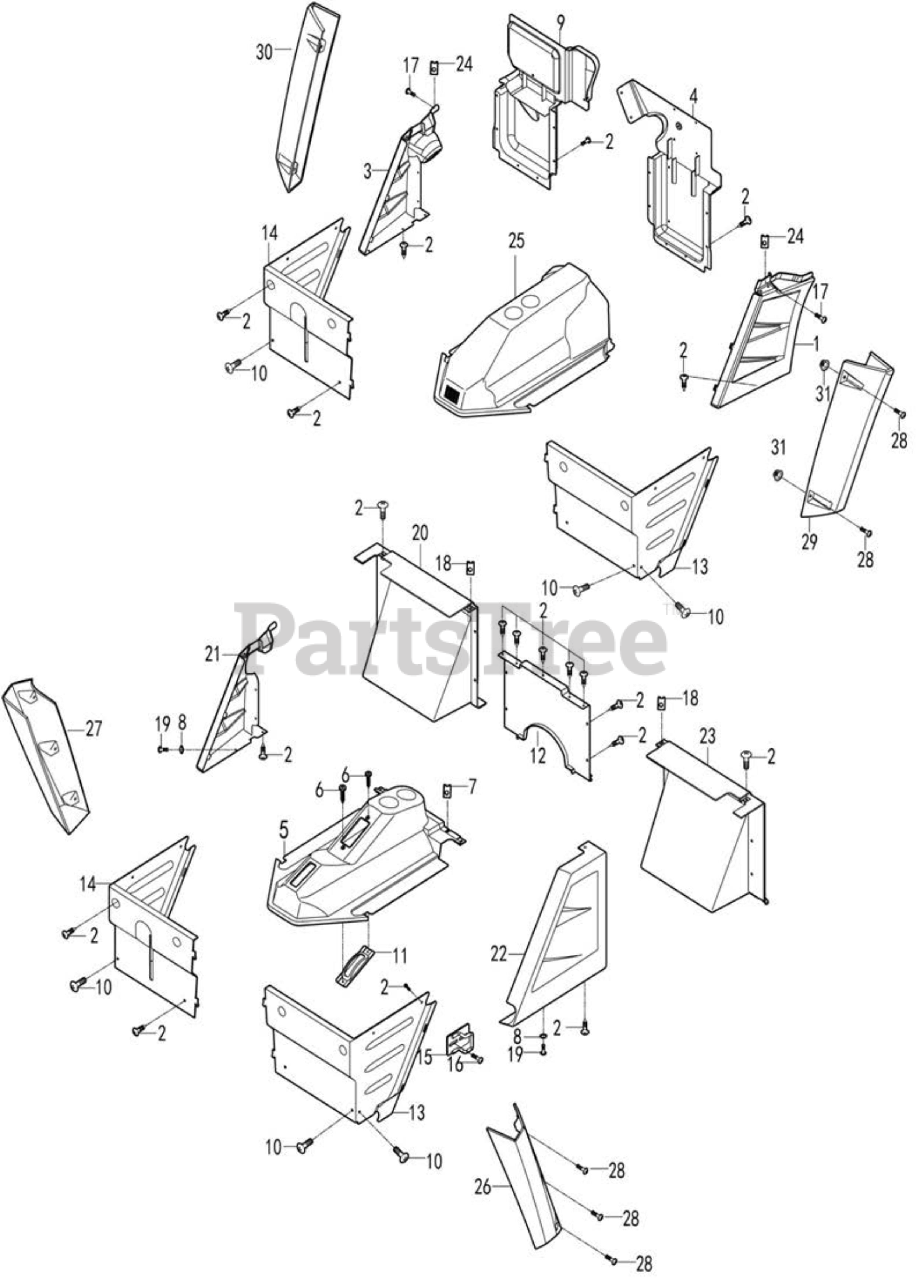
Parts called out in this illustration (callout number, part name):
1	Left Board I
2	Cross Large Plate Head Screw M6X16
3	Right Board I
4	Rear Fender I
5	Engine Cover Board
6	Socket Hexagon Flat Head Bolt M6X16
7	Nut clamp M6X2
8	Flat Washer 5
9	Rear Fender II
10	Expansion bolt(Plastic)
11	Parking Decorative Cover
12	Front Fender, Seat Cushion
13	Protective Plate under Seat
14	Lower Backplate, Seat Cushion
15	Door Locker Hook
16	Hexagon Flange Bolt M6X16
17	Cross Recessed Plate Head Screw M6X12
18	Nut clamp M6X2
19	Cross Large Plate Head Screw M5X16
20	Rear Right Backplate, Seat Cushion
21	Protective Plate(Left), Out of Cap
22	Protective Plate(Right), Out of Cap
23	Rear Left Backplate, Seat Cushion
24	Nut clamp M6
25	Middel Cover
26	Left fender, front cover
27	Right fender, front cover
28	Cross large plate head screw M6X20
29	Right fender, Rear body
30	Left fender, Rear body
31	Hexagon Flange Self-Lock Nuts M6
